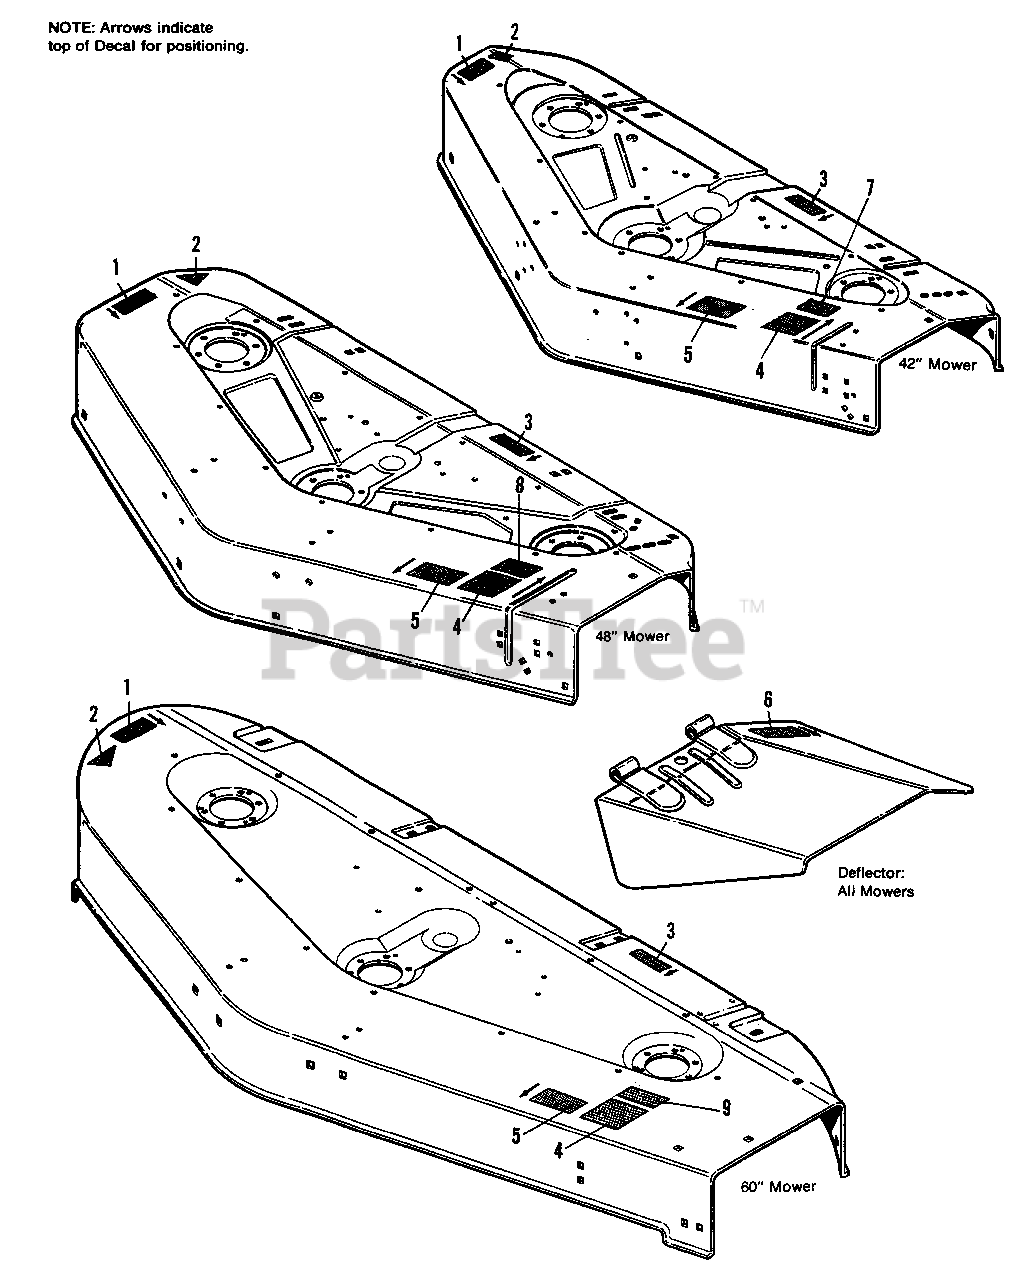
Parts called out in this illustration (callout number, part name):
1	DECAL, Danger
2	DECAL, OPEI
3	I.D. PLATE
4	DECAL, Danger, Mower
5	DECAL, Belt Instruction
6	DECAL, Cutting Line
7	DECAL, Cutting width (42")
8	DECAL, Cutting width (48")
9	DECAL, Cutting width (60")
